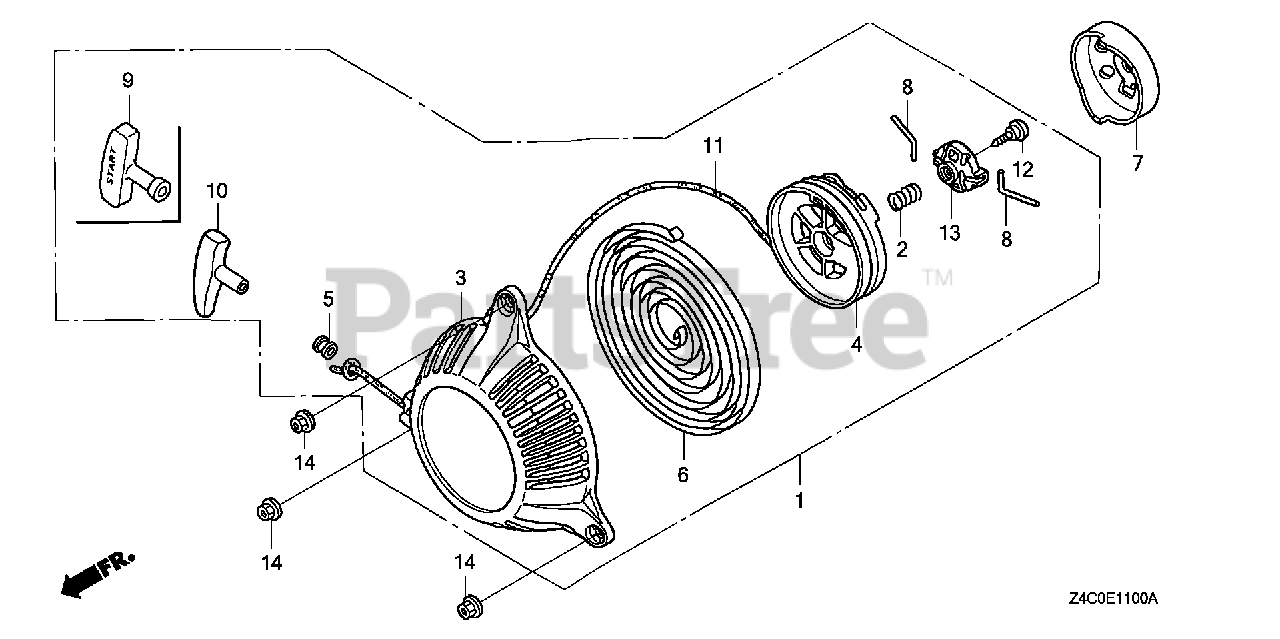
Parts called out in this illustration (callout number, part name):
1	STARTER ASSY., RECOIL
2	SPRING, FRICTION
3	CASE, RECOIL STARTER
4	REEL, RECOIL STARTER
5	GUIDE, ROPE
6	SPRING, RECOIL STARTER
7	PULLEY, RECOIL STARTER
10	KNOB, RECOIL STARTER
11	ROPE, RECOIL STARTER
12	SCREW, SETTING
14	NUT, FLANGE (5MM)
